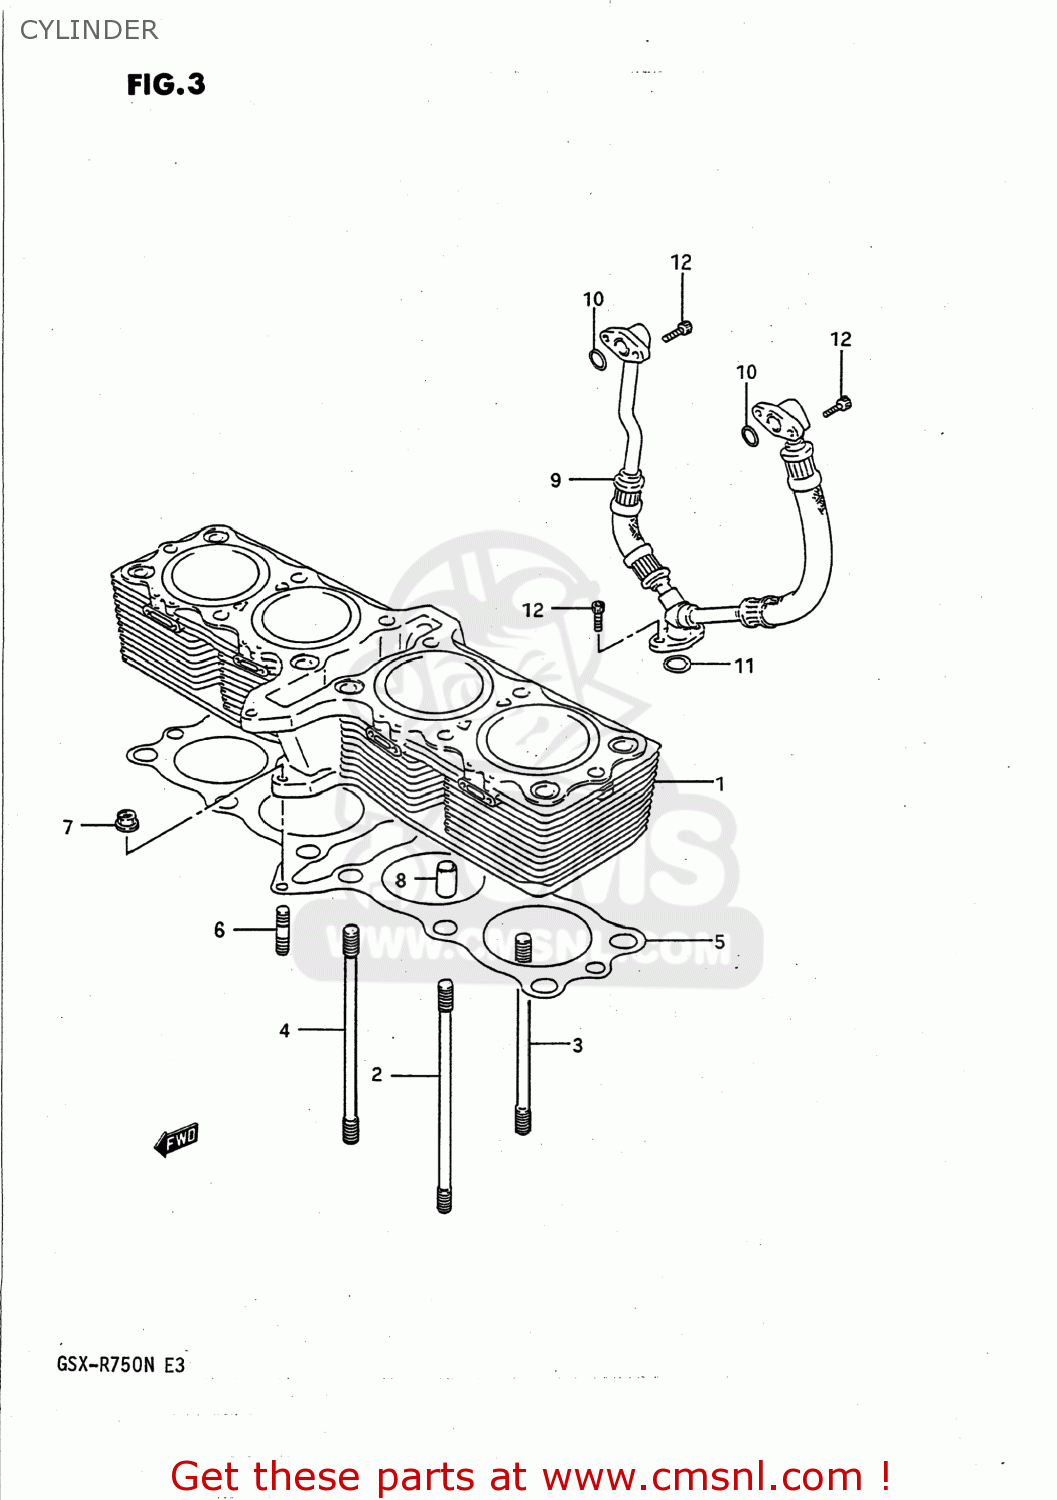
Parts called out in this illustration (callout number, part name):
1	CYLINDER
2	STUD BOLT (L:150)
3	BOLT,STUD
4	STUD
5	GASKET,CYLINDER (NAS)
6	STUD BOLT L:20
7	NUT 6MM
8	PIN
9	HOSE
10	O RING(D:2.5,ID:13.8)
11	O RING(D:2.4,ID:15.8)
12	BOLT
